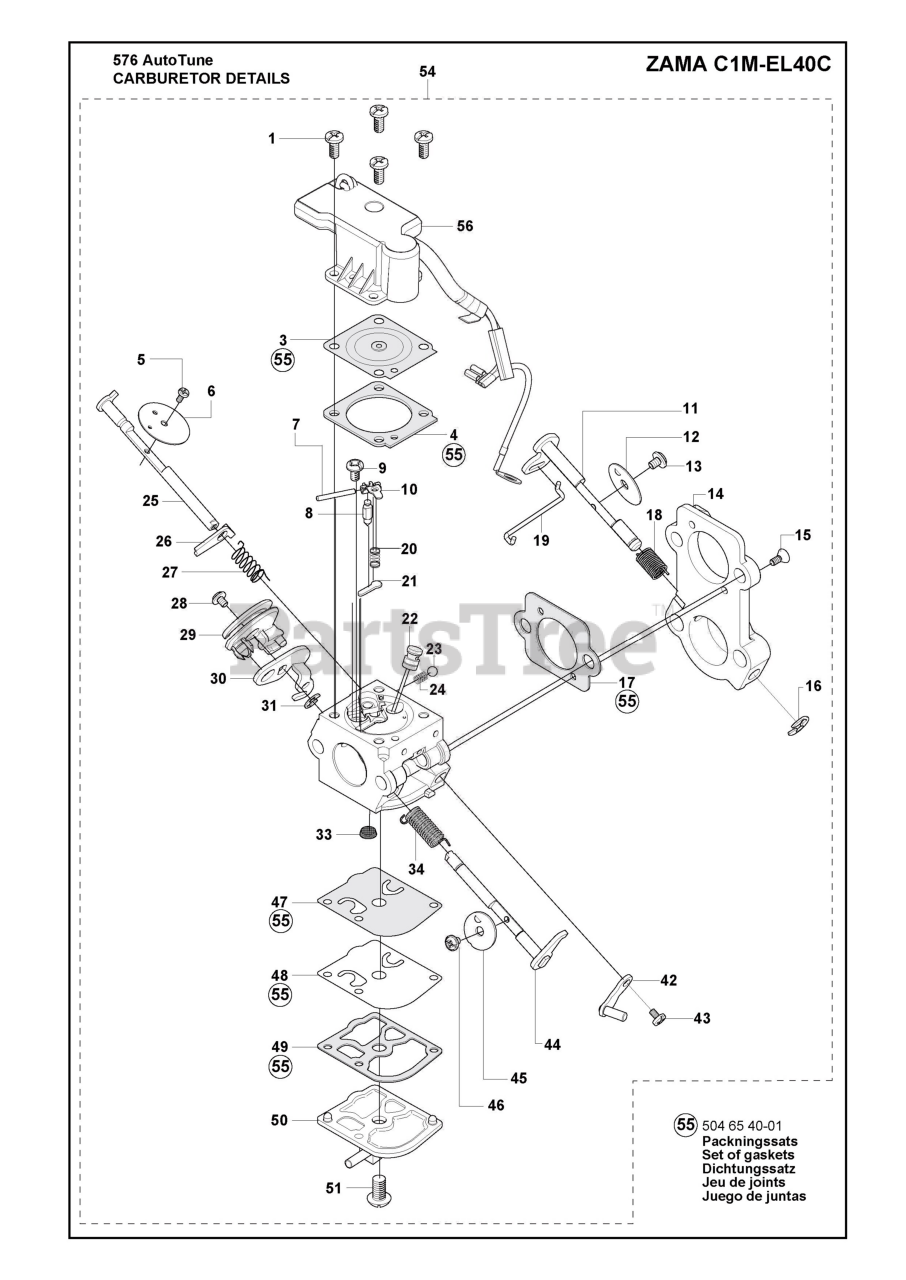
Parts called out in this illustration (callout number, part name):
4	GASKET METERING
6	CHOKE VALVE
7	PIN FULCRUM
8	INLET NEEDLE
12	THROTTLE FLAP
14	RP CARBURETOR
25	CHOKE SHAFT
26	LEVER
29	THROTTLE LEVER ASSY
38	NEEDLE HIGH SPEED
41	LOW SPEED NEEDLE
44	THROTTLE SHAFT
47	PUMP DIAPHRAGM
54	CARBURETOR
55	GASKET SET KIT
56	VALVE HOUSING ASSY
